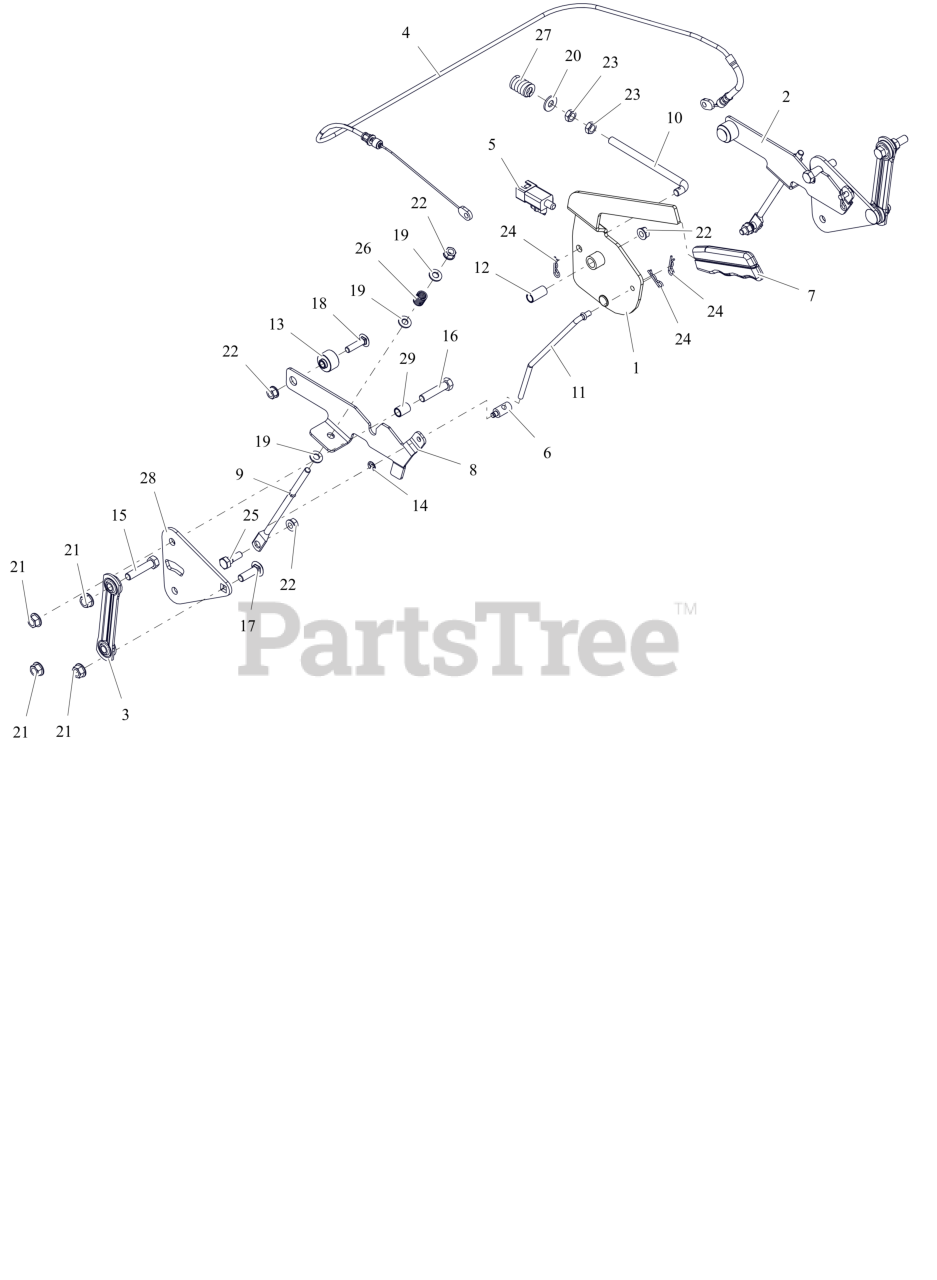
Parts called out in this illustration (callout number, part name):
1	LEVER, PARKING BRAKE
2	ARM, BRAKE - LH (W/PIN)
3	LINK, STAMPED STEERING
4	CABLE, BRAKE - PARKING
5	SWITCH, SNAP IN - N.O./N.O.
6	TRUNION, 1/4-20
7	GRIP, PARKING BRAKE (GREY)
8	ARM, BRAKE - RH
9	ROD, LINK - TRANSMISSION BRAKE
10	ROD, OVER CENTER
11	ROD, BRAKE LINK
12	BSHG-SLV .385X.500X1.045
13	SPCR, FLANGE
14	RG-RTNG-EXT .250X.025
15	BLT, HEX .38-16X1.75 G5 ZCC
16	BLT, HEX .38-16X1.75 G5 ZCC
17	BLT,RHSSN .38-16X1.25 G5 ZCC
18	BLT, RHSSN.31-18X1.25 G5 ZCC
19	WSHR,FLT .344X.688X.065 ZCC
20	WSHR,FLT .375X.875X.083 ZCC
21	NUT-LK-TOP-FLG .38-16 ZC120
22	NUT-LK-TOP-FLG .312-18 GF ZCC
23	NUT-JAM .375-16 G2 ZCC
24	PIN, HAIR #213 .08X1.19 ZCC
25	BOLT,SHLDR .38X.25 -.31-18X.75
26	SPRING, COMPRESSION
27	SG-COMP .187X.56X1.62
28	PLATE, TRANSAXLE (BLACK)
29	SPCR SLEEVED .385X.500X.718
